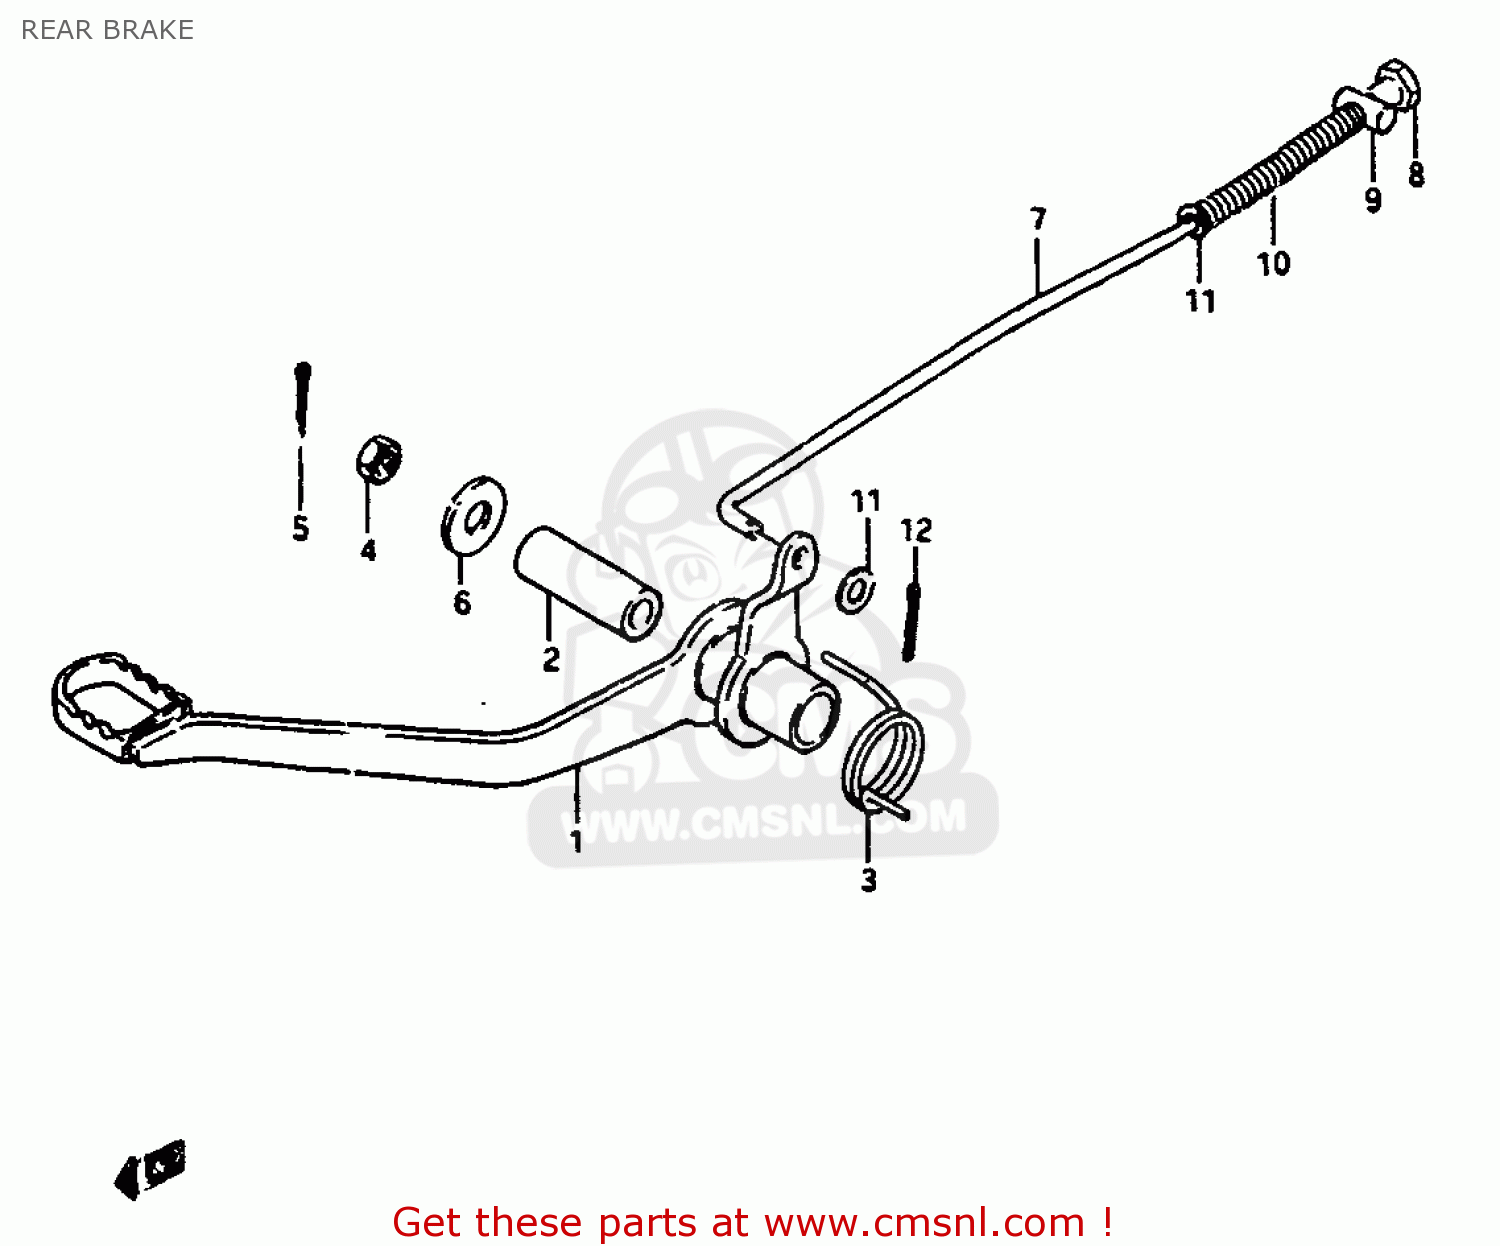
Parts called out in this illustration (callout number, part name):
1	PEDAL,BRAKE
2	SPACER,BRAKE PEDAL
3	SPRING,BRAKE PEDAL RETURN
4	NUT
5	PIN 25X20
6	WASHER
7	ROD ASSY,RR BRAKE
8	NUT
9	PIN,10X19
10	SPRING
11	WASHER
12	PIN
